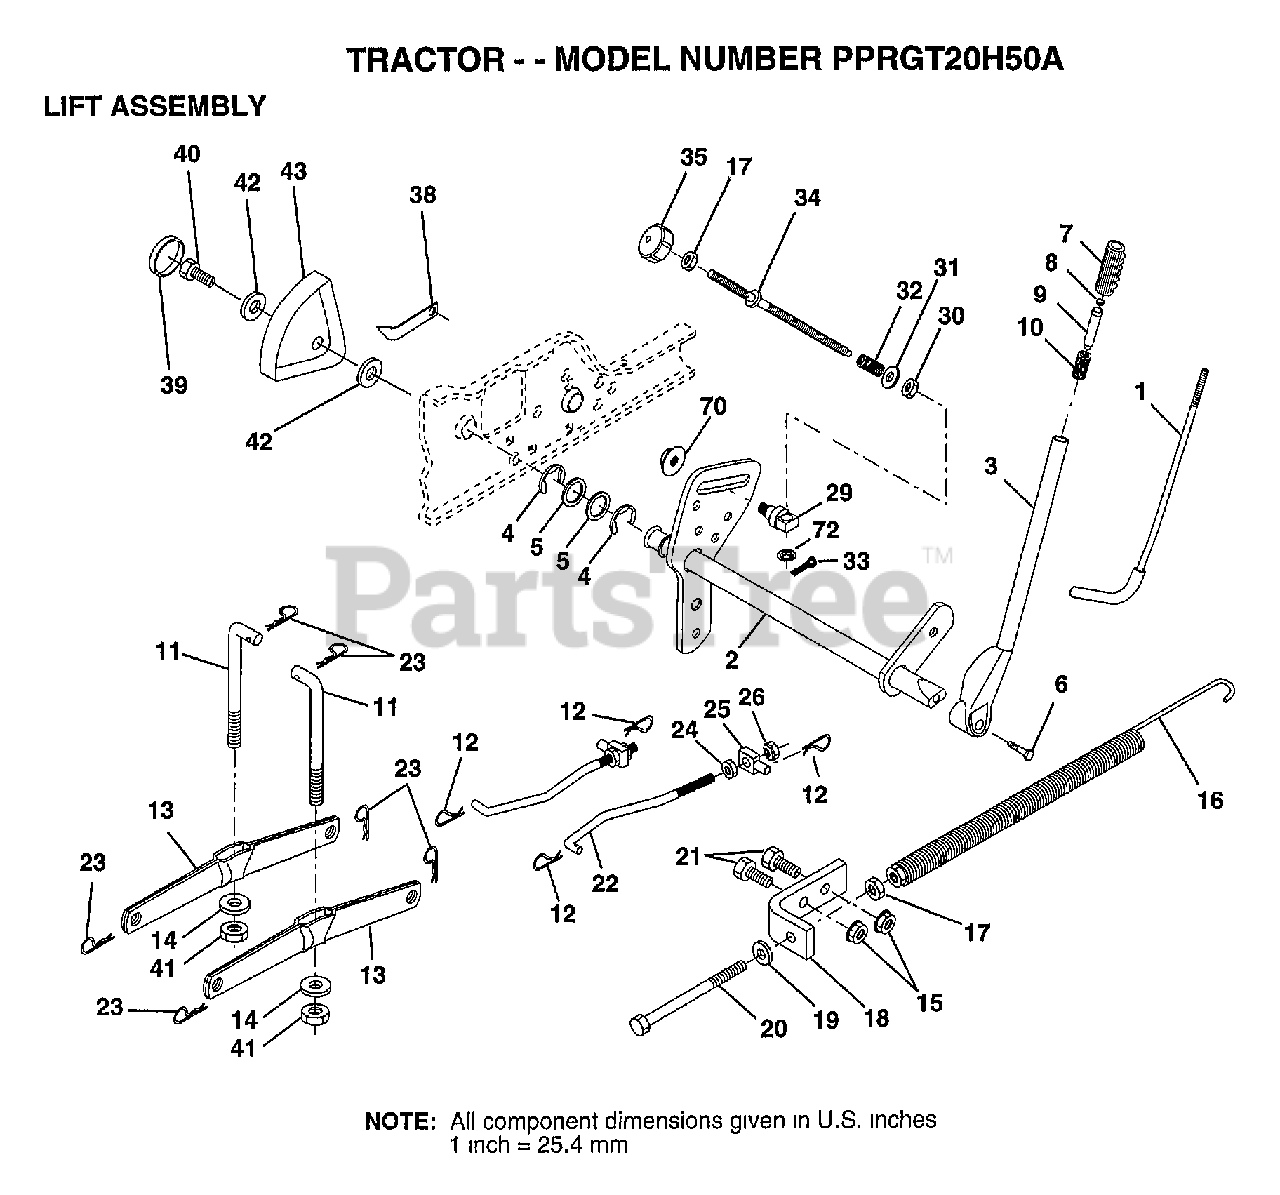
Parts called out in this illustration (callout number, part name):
1	LEVER ROD LT
2	SHAFT.ASM.LIFT.VGT
3	LEVER.ASM.LIFT.RH
4	E-RING
5	WASHER
6	"BOLT,HEX"
7	GRIP HANDLE
10	SPRING T
11	LINK.LIFT.MWR.VGT
12	RETAINER SPRING
13	ARM SUSP REAR
14	BEARING PVT LH
17	NUT
18	BRACKET SPRING AS
19	WASHER
20	BOLT-ADJ SPRING T
21	BOLT
22	LINK.FRONT
24	NUT
25	TRUNION
26	NUT LTV
29	TRUNNION
30	NUT T
31	WASHER
32	SPRING.COMP.INF.H
34	ROD.ADJ.LIFT
35	KNOB INF 3/8-16
38	POINTER-INDICAT
39	"PLUG,HOLE"
40	SCREW
41	NUT.CROWNLOCK.3/8
42	WASHER
43	HEIGHT INDICATOR
70	NUT.HXFLG.LOCK.
72	NUT PUSH M
